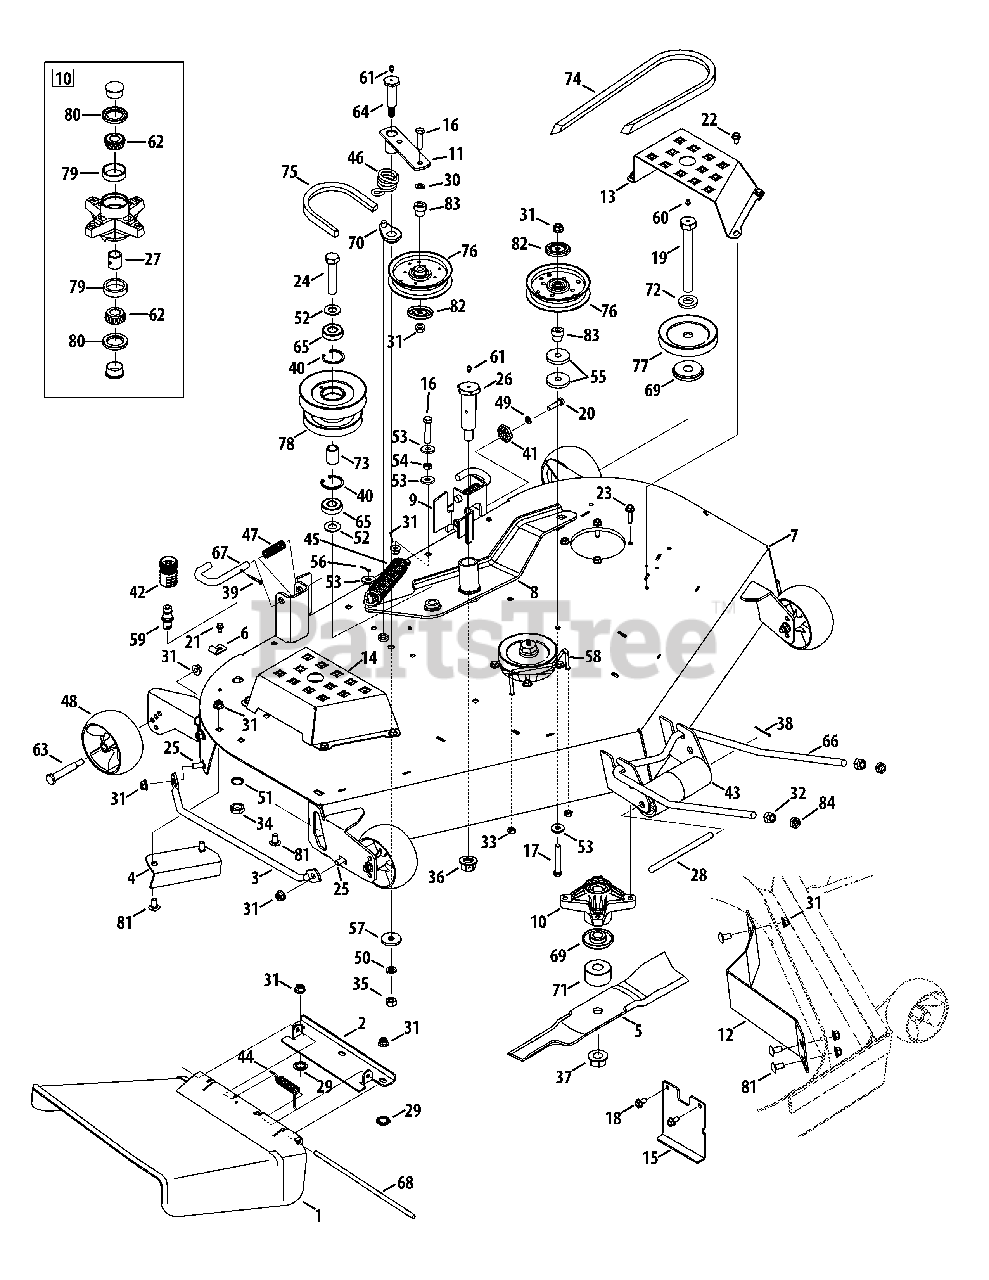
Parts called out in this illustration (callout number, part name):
1	Chute Deflector
2	Chute Bracket
3	Finger Guard
4	Micro Chute Baffle
6	Hook Retainer Bracket
7	Deck 48"
9	Hanger Adjustment Bracket
10	Spindle Assembly
15	Up-Stop Bracket
16	Hex Screw, 3/8 x 16 x 1.75
17	Hex Screw, 3/8-16 x 2.50
18	Hex Washer, 5/16-18 x .750
19	Hex Screw, 3/4-16 x 6.00
20	Hex Screw, 5/16-18 x 1.25
21	Hex Washer Screw, 1/4-20 x .500
22	Hex Washer Screw, 5/16-18 x .625
23	Hex Washer Screw, 5/16-18 x 1.50
24	Hex Screw, 5/8-18 x 3.00
25	Carriage Bolt, 3/8-16 x 1.00
26	Shoulder Screw, 1.0 x 3.00
27	Bearing Spacer, .78 x 1.0 x 1.0425
28	Roller Pin, 1/2 x 7.31
29	Push Nut, 3/8
30	Flat Washer, .375 x .738 x .063
31	Flange Lock Nut, 3/8-16
32	Hex Nut, 1/2-13
33	Hex Lock Nut, 1/4-20
34	Hex Nut, M16-1.5
35	Hex Nut, 7/16-14
36	Flange Lock Nut, 5/8-18
37	Flange Lock Nut, 3/4-16
38	Cotter Pin, 3/32 x 1.25
39	Cotter Pin, 5/32 x 1.25
40	Retainer Ring
41	Deck Adjustment Gear
42	Water Nozzle Adapter
43	Front Roller
44	Torsion Spring, 180 x .639 x 2.16 x .12
45	Extension Spring, 1.25 x 6.9
46	Idler Torsion Spring, 1.10 x 1.3
47	Compression Spring, .66 x 1.8
48	Deck Wheel, 5.0
49	Lock Washer, 5/16
50	Lock Washer, 7/16
51	Lock Washer, 5/8
52	Flat Washer, .65 x 1.25 x .075
53	Flat Washer, .385 x 1.0 x .135
54	Jam Nut, 3/8-16
55	Flat Washer, .4375 x 1.75 x .25
56	Cotter Pin, 3/32 x .75
57	Flat Washer, .45 x 1.5 x .172
58	Belt Drive Guard
59	Deck Water Nozzle
60	Grease Fitting, 1/4-28 x 3/16
61	Drive Lube Fitting, 3/16
62	Cone Bearing, .750
63	Shoulder Screw, 1/2 x 2.50
64	Shoulder Screw, 7/16-14 x .687 x 2.443
65	Ball Bearing, .625 x 40 x 12
66	Front Hanger Rod
67	Mower Support Pin
68	Chute Deflector Rod
69	Spindle Spacer
70	Spring Retainer
71	Spindle Spacer, .760 x 2.0 x 1.10
72	Spacer, .812 x .218
73	Spacer, .88 x .635 x 1.25
76	Idler Pulley
78	Double Pulley
79	Bearing Cup, .750
81	Carriage Bolt, 3/8-16 x .75
82	Pulley Cap
83	Shoulder Spacer, Idler
84	Nut, Jam, 1/2-13
